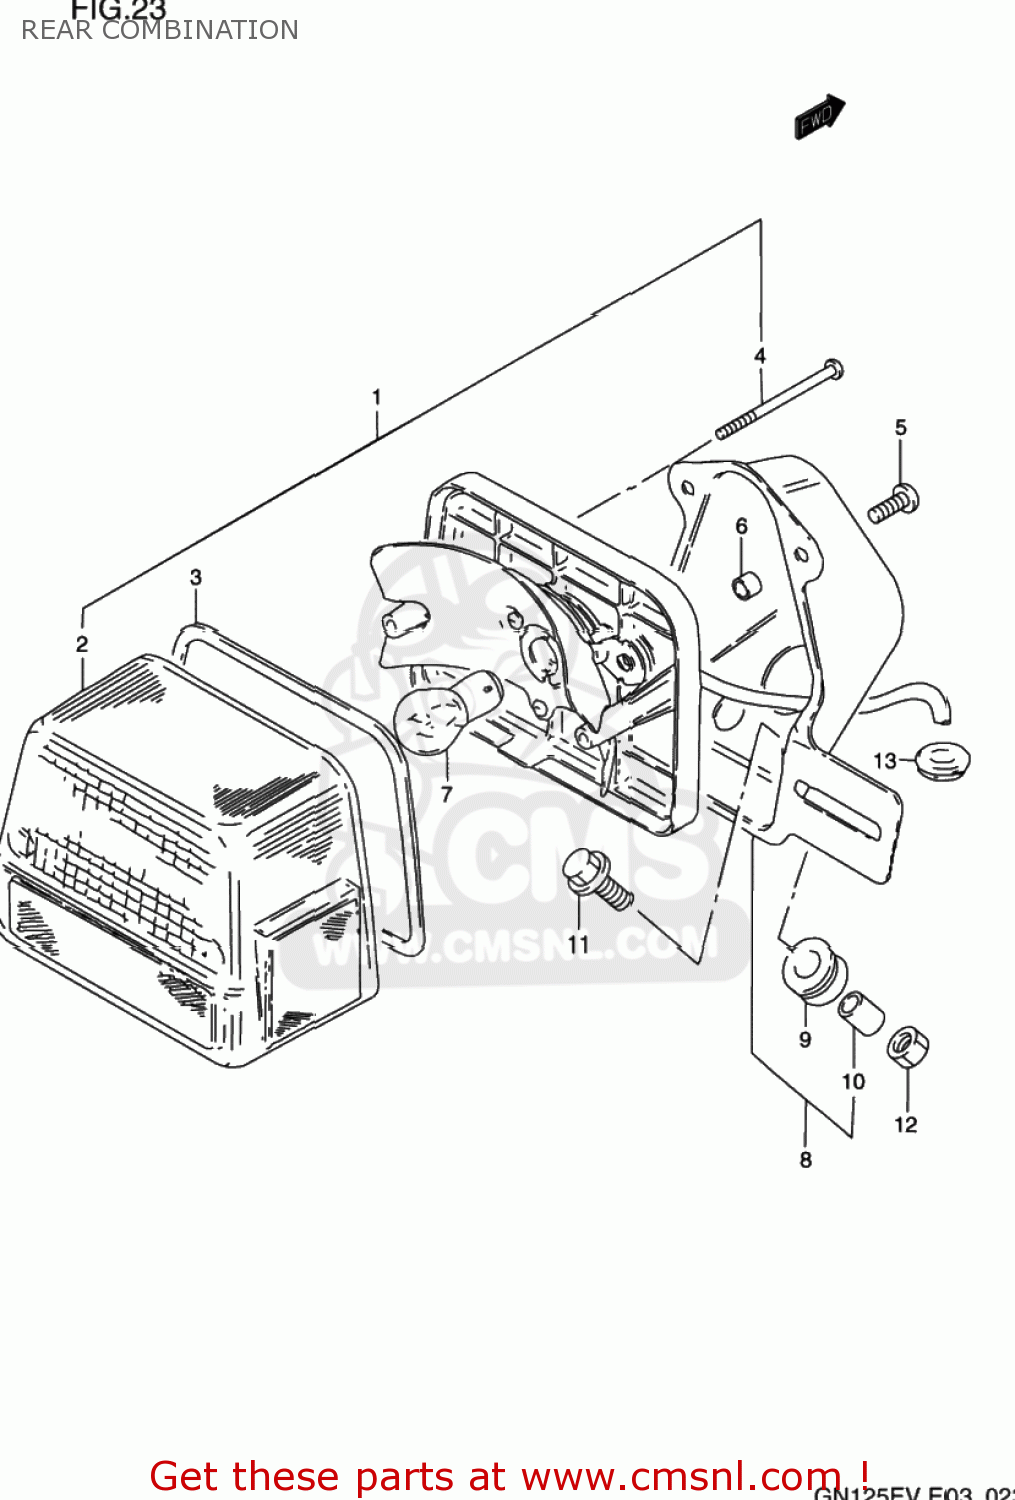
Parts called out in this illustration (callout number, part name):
1	LAMP UNIT,RR COMBNATION
2	LENS
3	GASKET (NAS)
4	SCREW
5	SCREW
6	SPACER
7	BULB(12V23W)
8	BRACKET UNIT,TAIL LAMP
9	CUSHION
10	SPACER
11	BOLT(6X25)
12	NUT 6MM
13	GROMMET
